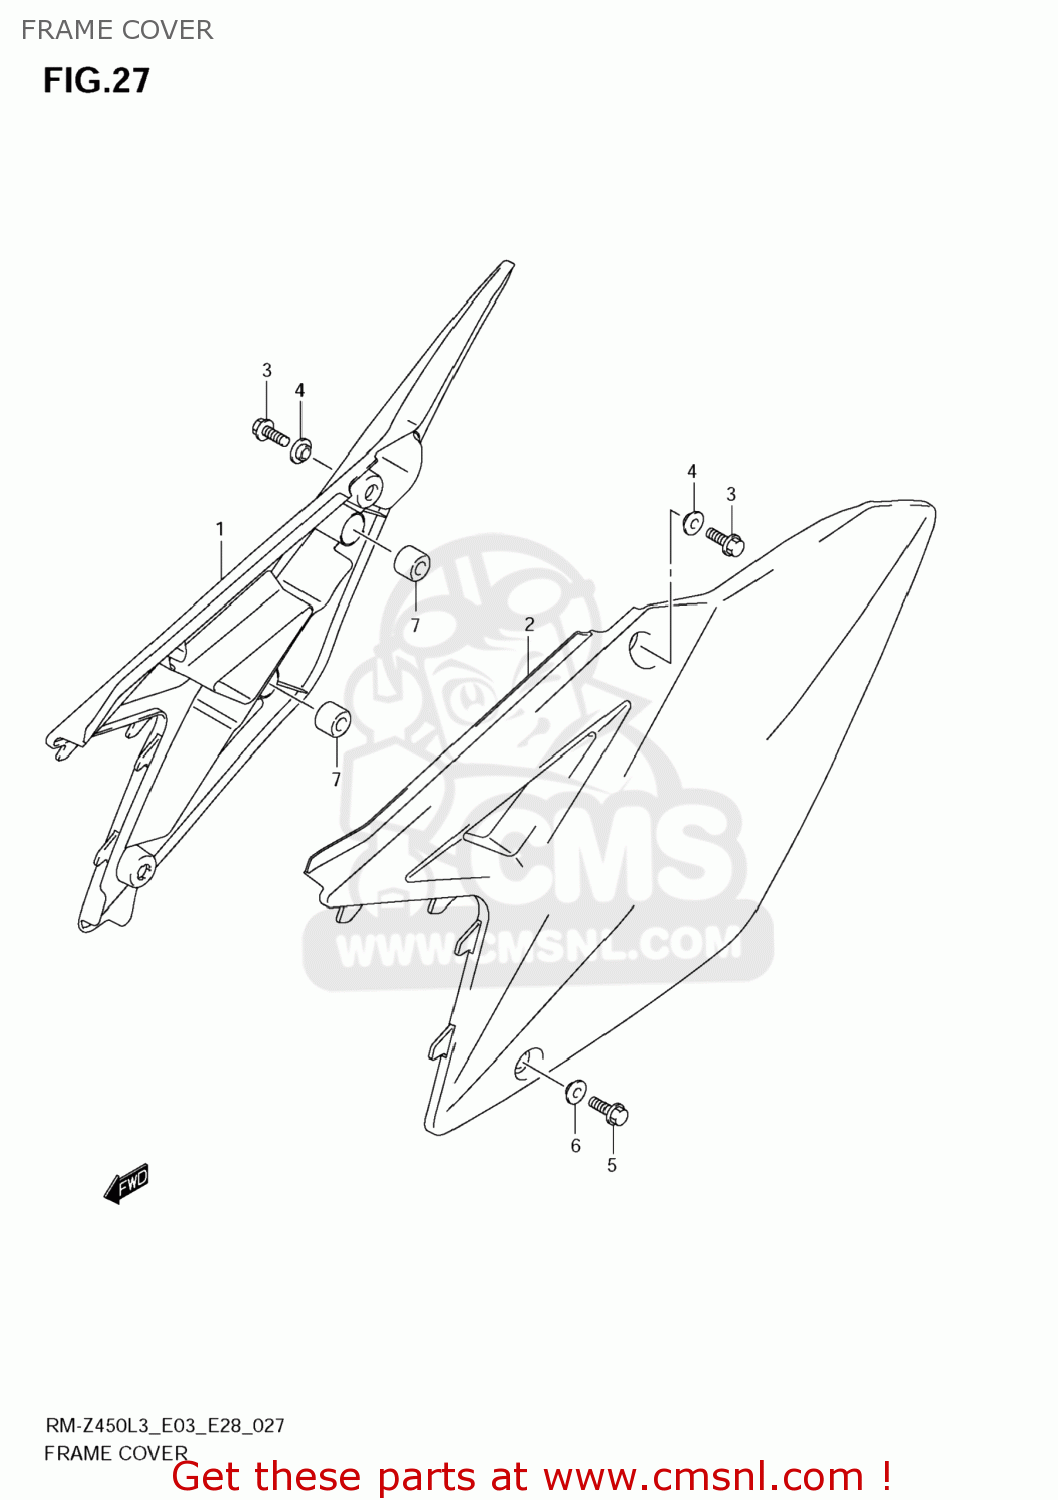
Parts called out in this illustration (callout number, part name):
1	COVER,FRAME,R(WHITE)
2	COVER,FRAME,L(WHITE)
3	BOLT
4	WASHER,FRAME COVER & SEAT
5	BOLT
6	WASHER,FRAME COVER & SEAT
7	CUSHION
